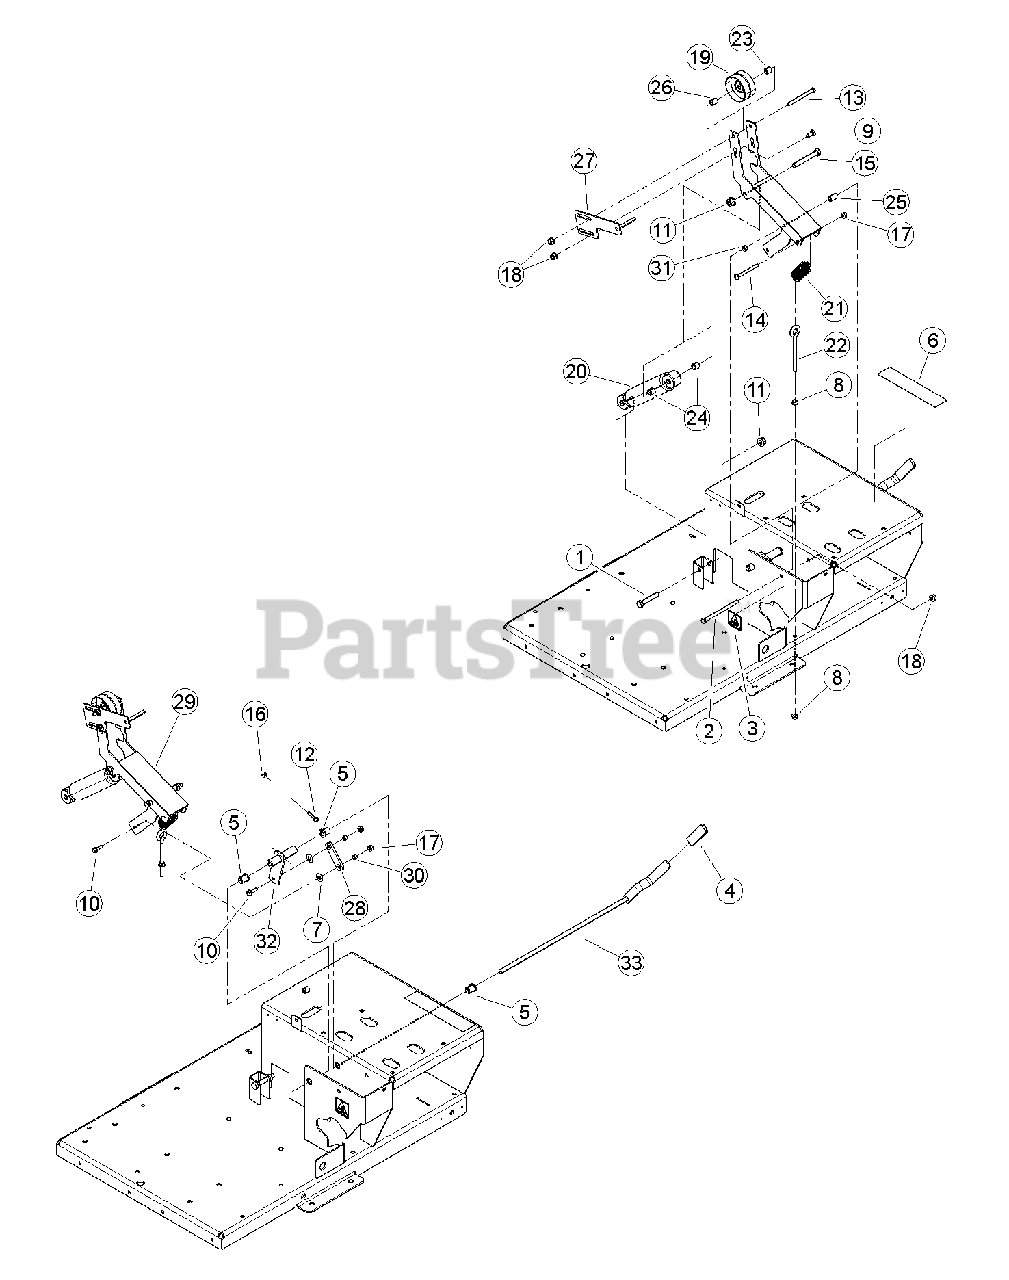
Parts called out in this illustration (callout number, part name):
1	BOLT, 1/2 X 2-3/4 HEX GR5 ZP
2	BOLT, 3/8 X 5-1/2 HEX GR5 ZP
3	DECAL, SHIELD DANGER ISO
4	GRIP, CLUTCH HANDLE
5	BUSHING, 1/2 X 1 FLANGE LUBE
6	DECAL, CHIPPER ENGAGEMENT
7	NYLON WASHER, 1/2 INCH
8	NUT, 3/8" SERRATED FLANGE NC ZP
9	BOLT, 3/8 X 1" CRG GR5 NC ZP
10	BOLT, 5/16 X 1 FLANGE NC
11	NUT, 1/2-13 NYLOCK FLANGE
12	BOLT, 1/4 X 1-1/4 FLANGE NC
13	BOLT, 3/8 X 4" HHCS GR5 NC ZP
14	BOLT, 5/16 X 3-1/2 CRG GR5 ZP
15	BOLT, 1/2 X 3-3/4 HHCS GR5 NC ZP
16	NUT, 1/4-20 NYLOCK-FLANGE
17	NUT, 5/16-18 NYLOCK-FLANGE
18	NUT, 3/8-16 NYLOCK-FLANGE
19	PULLEY, 3-1/4 FLAT IDLER
20	ABSORBER, IDLER SHOCK
21	SPRING, 1.25 OD X 3.50 LG X .148 WD
22	EYEBOLT, 3/8" X 5" LG 4-1/4 THD ZP
23	SPACER, .63 X .63 PULLEY
24	SPACER, .75 X .59
25	SPACER, .63 X 1.035
26	SPACER, 5/8 OD X 11 GA X .760
27	WELDMENT, PIVOT ROD
28	PLATE, CONNECTING ARM
29	WELDMENT, IDLE ARM
30	SPACER, 1/2" OD X 14 GA WA
31	SPACER, 5/8" OD X 3/8" ID X 0.28"
32	WELDMENT, PIVOT ARM
33	WELDMENT, HANDLE
